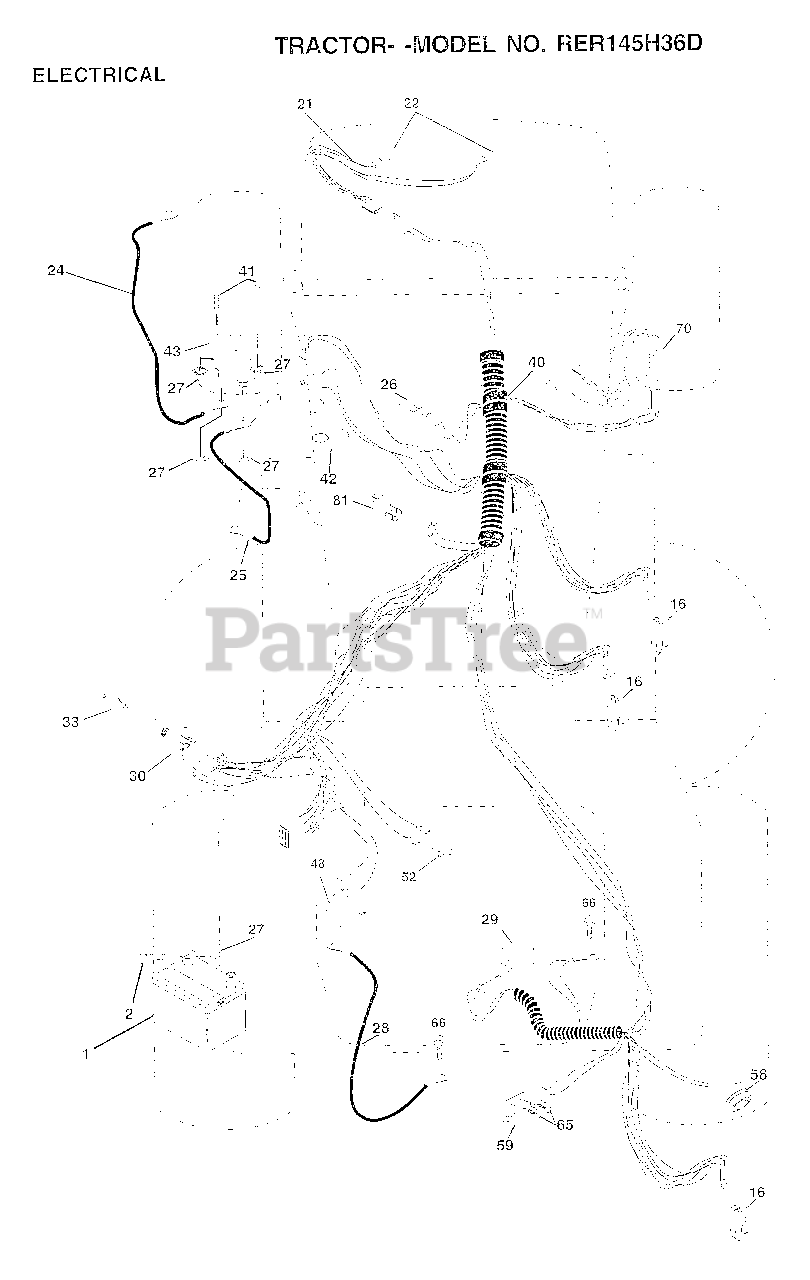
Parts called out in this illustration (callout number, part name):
2	BOLT LT
16	SWITCH INTERLOCK
21	HARNESS.ASM.LIGHT W/4152J
22	HEADLAMP BULB
24	"CABLE T, BATTERY"
25	CABLE.BATTERY.CRD
26	FUSE.15 AMP
27	NUT
28	"CABLE.GRD.6GA/18""BLACK"
29	SWITCH.PLUNGER
30	SWITCH.IGN.
33	KEY MLD GEN DELTA
40	HARNESS IGN CORD
41	BOLT HXHD FIN
48	ADAPTER AMMETER
52	PROTECTION LOOP
58	BUZZER CRD
59	SWITCH.FBI.CRD
65	SCREW
66	SCREW LT
70	HARNESS
81	RELAY ASSY T
